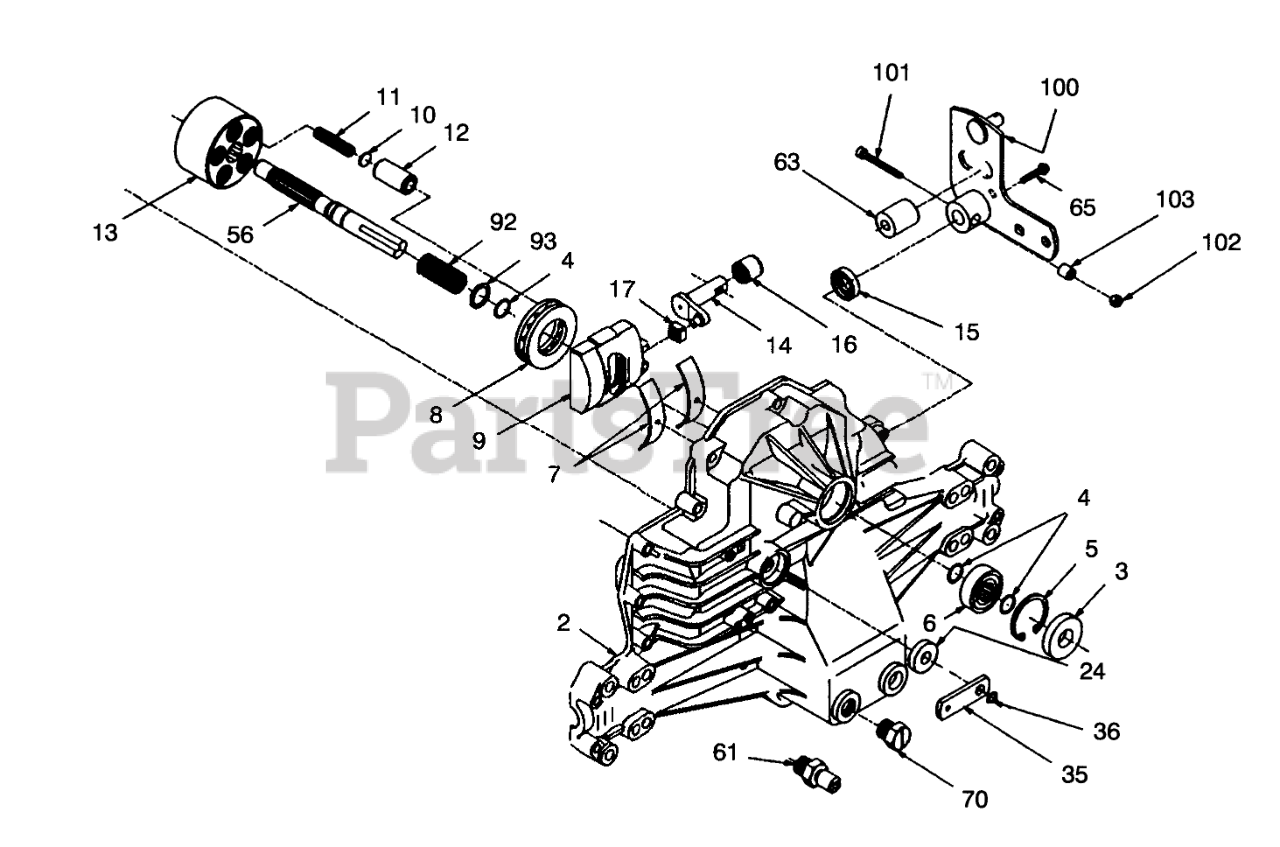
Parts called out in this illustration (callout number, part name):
2	Housing-Upper
3	Seal-Lip
4	SEAL-LIP
6	Bearing-Shaft Ball
7	Bearing-Cradle
9	Swashplate-Variable
10	Washer-Piston Thrust
11	Spring-Piston
13	Block Cylinder (Motor)
14	Arm-Trunnion
15	SEAL-LIP
16	Bearing-Trunnion Journal
17	Guide-Slot
24	SEAL-LIP
26	Plate-Bypass
35	ARM - BYPASS
36	RING-RETAINING
61	BREATHER ASSEMBLY
65	Bolt
70	Plug-Plastic
92	Spring-Block
93	Washer-Block Thrust
100	Control Arm Ass-y
101	SCREW-HSH
102	NUT-LOCK, NI
103	LOCK SPACER
